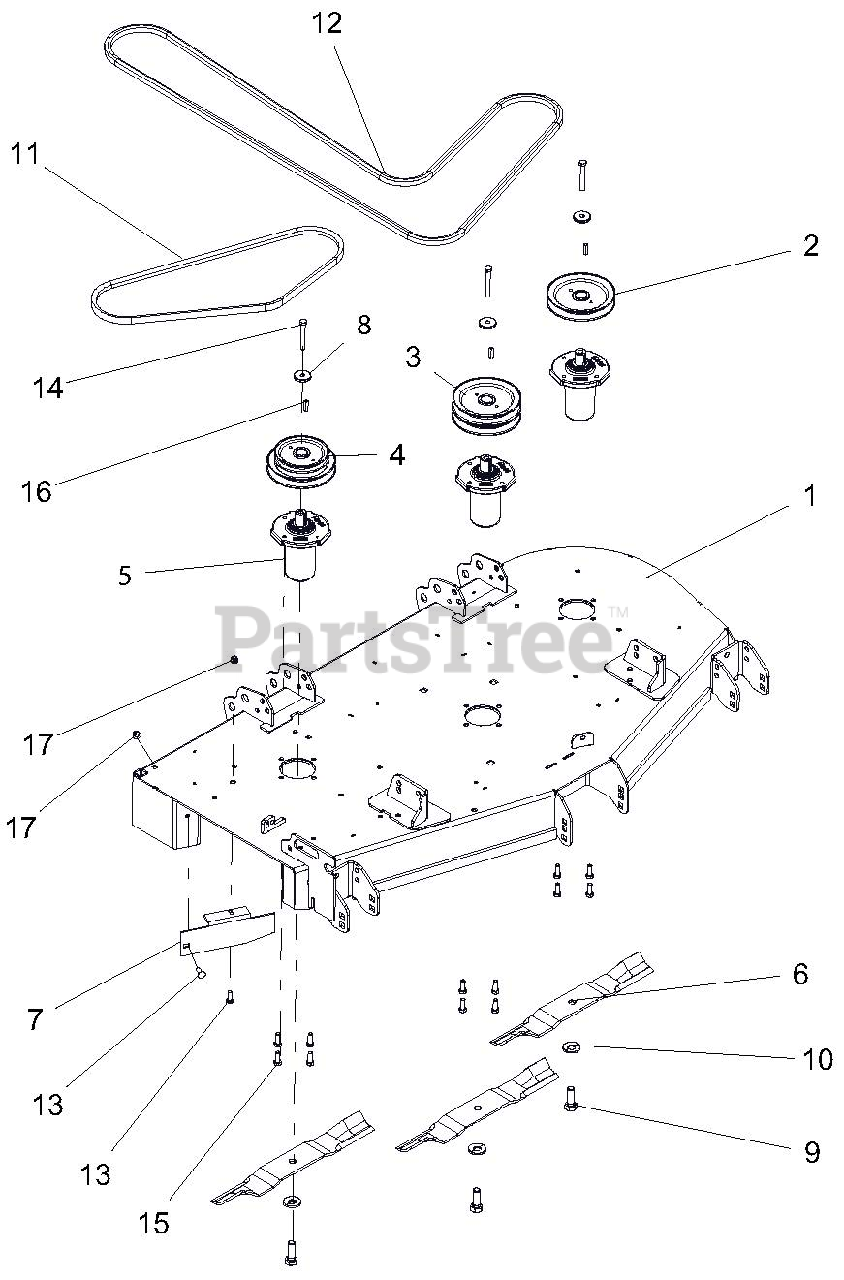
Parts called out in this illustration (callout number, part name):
1	KIT, 52" MOWER DECK W/SAFETY DECALS-RED
2	PULLEY, SINGLE -1" ID X 6.00" OD-BLACK
3	PULLEY, DOUBLE -1" ID X 6.00" OD-BLACK
4	PULLEY, DOUBLE -1" ID X 6.00" & 4.75" OD
5	SERVICE, ASM SPINDLE- DUCTILE
6	BLADE, 18"
7	BAFFLE, DISCHARGE, 52"-RED
8	RETAINER, SHEAVE SPINDLE
9	BLT, HEX .62-18X1.75 GR8 YWZC
10	WSHR, BLVL .63X1.625X.14
11	BELT, B 56.00 RAW COGGED
12	BELT, BB 118.00 WRAPPED HEX
13	BLT-RDHDSQSHNK .31-18X1.00 G5 Y
14	BLT-HEX .38-16X2.75 GR8 YWZC
15	BLT-HEX .38-16X1.00 GR5 YWZC EP30
16	KEY-SQ .250X.250X1.00 RC 40-50
17	NUT-LK-NYL-FLG .31-18 YWZC
